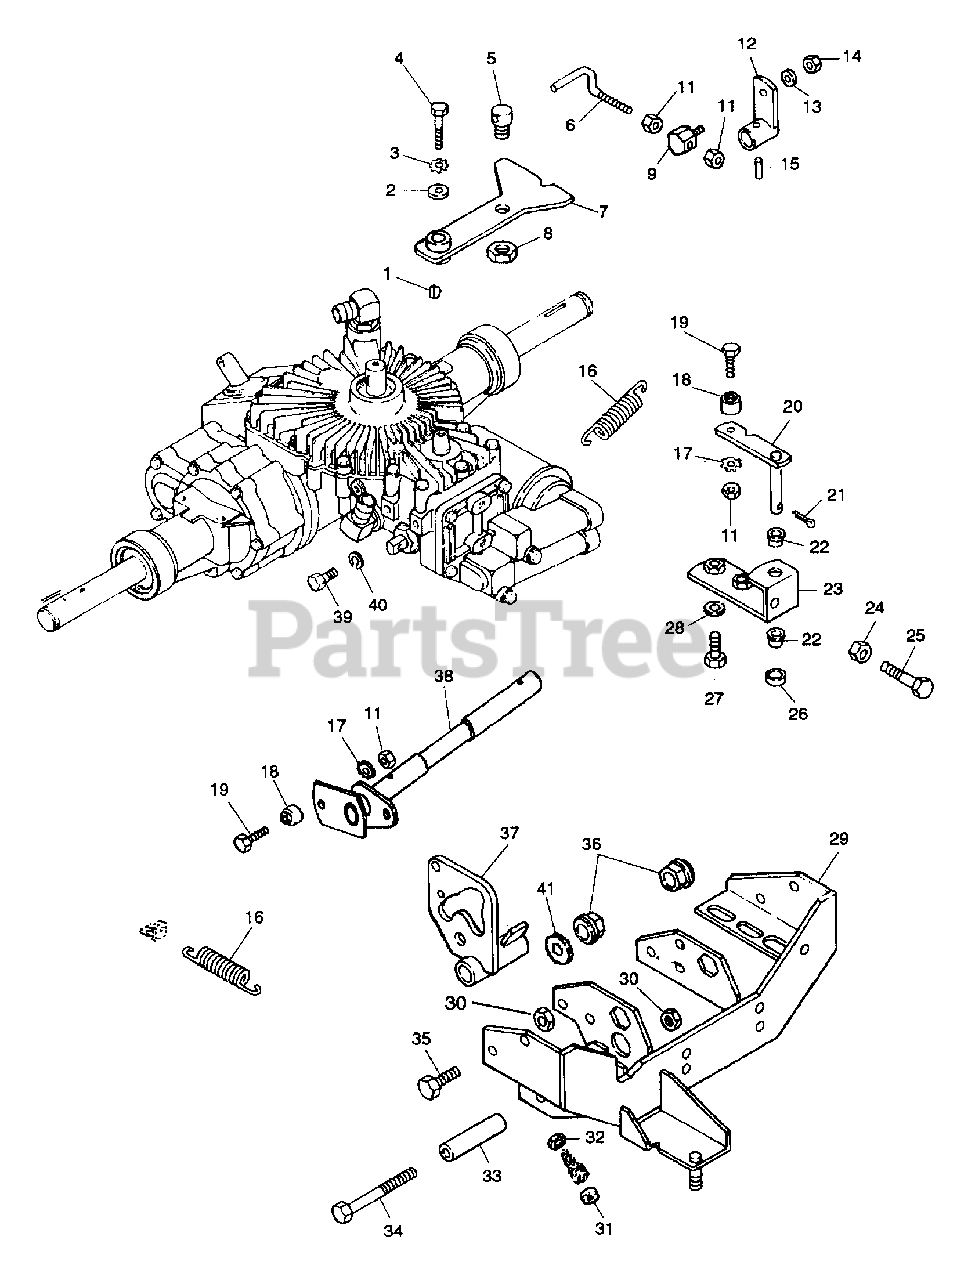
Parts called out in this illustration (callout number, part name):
1	KEY-WDRF .125X.500X.203 SAE 3
2	WSHR-FL-STL.312X.734X.065PL
3	WSHR-LK-EXT. 250 ID
4	BLT-HEX .25-20X1.50 PL GR5
5	ADAPTER
7	CONTROL ARM
8	NUT-LK-CTR .50-13
9	ROD PIVOT
11	NUT-LK-CTR .250-20 PL
12	ARM & HUB
13	WSHR-FL-STL .323X.625X.062 PL
14	NUT-LK .312-18 GR A PL
15	PIN-ROLL .125X.88
16	SG-TENS .080X.73X3.06 WLD 20
17	WSHR-LK .250X.047 LT PL
18	BRG BALL DBL .250X.638X.438
19	BLT-HEX .25-20X1.00 GR2
20	PIVOT ARM
21	PIN-COTR .12X1.0 PL
22	BSHG-FLG .500X.375X.500X.687
23	PIVOT BRACKET
24	NUT-LK-CTR .375-16 GR A PL
25	BLT-HEX .38-16X1.75 PL GR2
26	BSHG-SLV .377X.624X.235
27	BLT-HEX .38-16X.75 PL GR2
28	WSHR-FL-STL .382X.812X.062
29	TORQUE MOUNT
30	NUT-LK TOP .375-16 GR C YWZC
32	NUT-HEX .625-32 PL
33	SPACER .390X.750X2.761
34	BLT-HEX .38-16X3.50 PL GR5
35	BLT-HEX .38-16X.75 PL GR5
36	BSHG-FLG .625X.875X.750X1.19HX
38	CROSS SHAFT
39	BLT-HEX .31-18X.63 PL GR 2
40	WSHR-LK-EXT .313X.030 PL
41	WSHR-FL-STL .630X1.005X.062 PL
